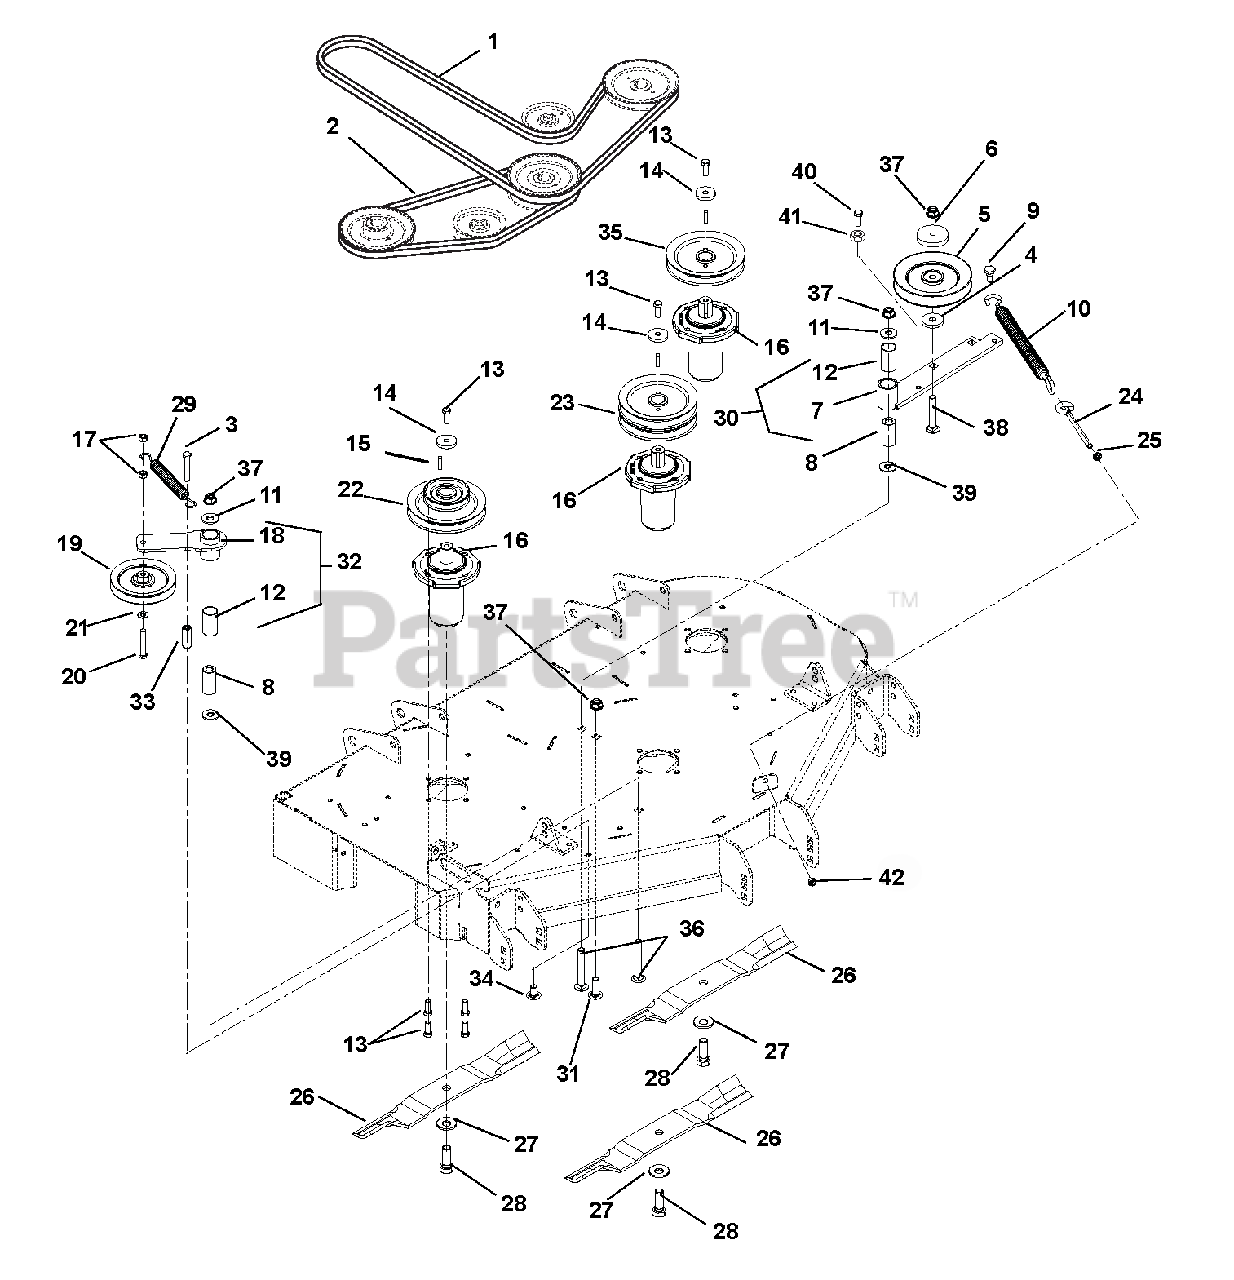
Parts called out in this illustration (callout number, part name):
1	HEX BELT, BB-WRAPPED
2	V-BELT, B-COGGED
3	@BLT-HEX .38-16X1.50 GR5 YWZC
4	BSHG, SPCR .502X.997X.50 PM
5	SHV, .50"ID X 6.00"OD V-IDLER
6	CAP, IDLER BEARING SEALING
7	WMT, IDLER ARM
8	BSHG, SPCR .502X.997X2.03 PM
9	BLT,SHLDR EP .38-16X.30 HEX YZ
10	SPRING, EXTENSION
11	@WSHR-FL-STL.563X1.38X.109YWZC
12	BSHG, 1.00 X 1.125 X 1.937
13	BLT-HEX .38-16X1.0 GR8 YZ EP30
14	WSHR,FLT STL.406X1.50X.245YWZC
15	KEY, SQ .25X.25X1.00 RC 40-50
16	ASSEMBLY, SPINDLE
17	@NUT-LK-CTR .38-16 YWZC
18	WMT, IDLER ARM
19	SHV, .38"ID X 5.00"OD V-IDLER
20	@BLT-HEX .38-16X2.25 GR5 YWZC
21	@WSHR-FL-STL.406X.812X.065 YWZ
22	PULLEY, DBL-1"IDX5.75"&3.50"OD
23	PULLEY, DOUBLE-1"ID X 5.75"OD
24	BOLT, .38-16X4.50 .62 DIA EYE
25	NUT-HEX-JAM .375-16 YWZC
26	BLADE, 16.19" MOWER (HI-LIFT)
27	WSHR-BLVL .669X1.535X.138
28	BLT-HEX .62-18X1.75 GR8 YWZC
29	SPRING, EXTENSION
30	ASM, IDLER PIVOT ARM (PTO)
31	BLT-RDHDSHSQNKFT.50-13X1.50 G5
32	ASM, IDLER ARM (DECK)
33	NUT COUPLING .375-16X1.75
34	@BLT-RDHDSHSQNK.38-16X1.0 G5YZ
35	PULLEY, V-1" ID X 5.75" OD
36	@BLT-RDHDSQNK .50-13X3.50 G5YZ
37	@NUT-LK-NYL-FLG .50-13 YWZC
38	@BLT-RDHDSQNK .50-13X3.00 G5YZ
39	WSHR-FLT .640X1.75X.250
40	@BLT-HEX .38-16X2.75 GR5 YWZC
41	@NUT-HEX .38-16 YWZC
42	@NUT-LK-CTR-JAM .375-16 YWZC
